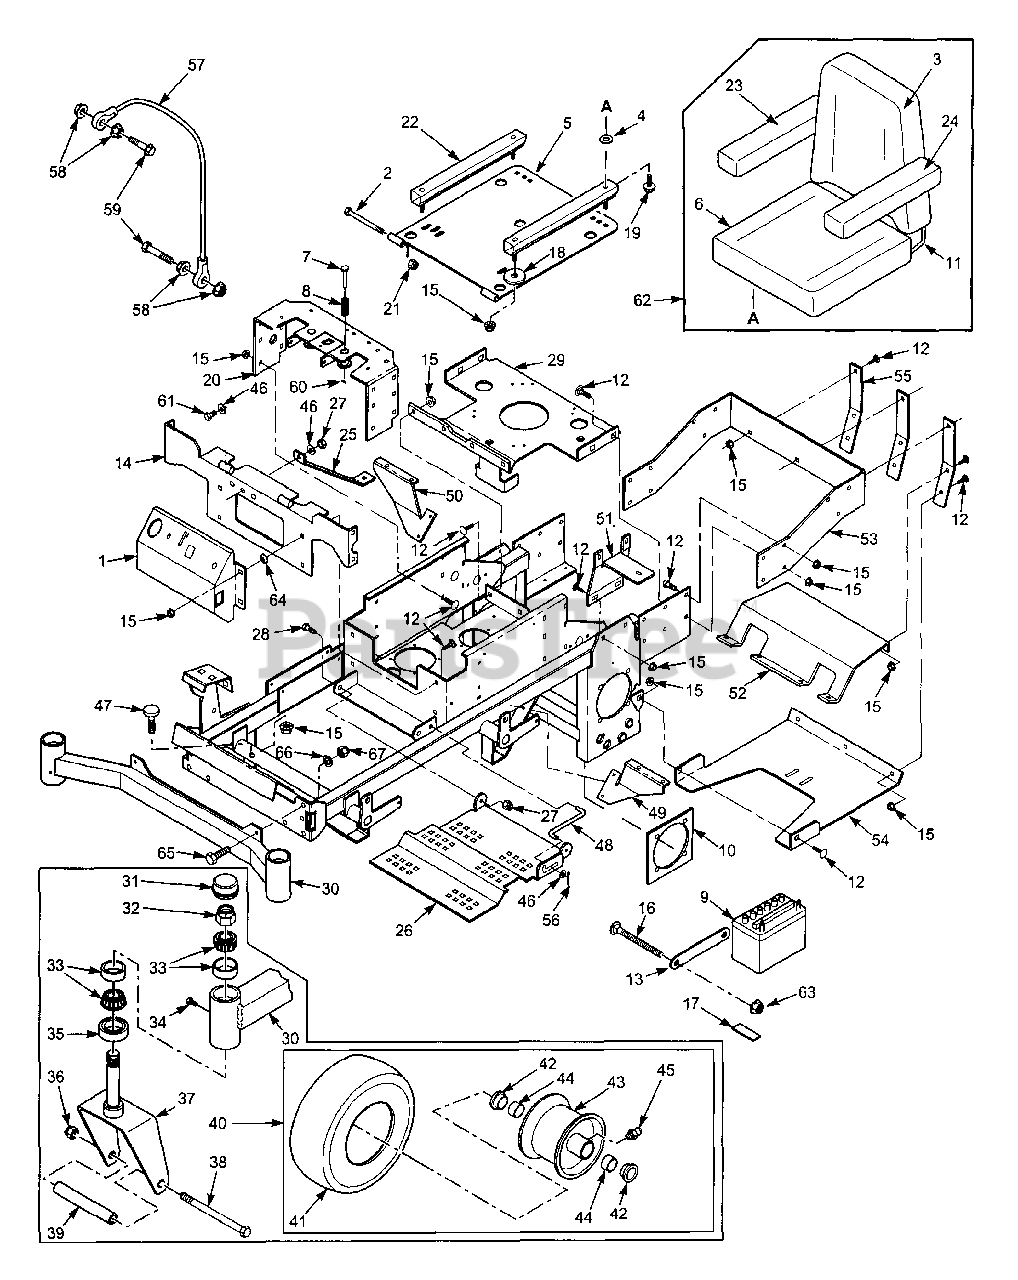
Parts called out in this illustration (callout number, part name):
1	Panel, Instrument
2	Bolt, Hex Head 5/16-18 x 3-1/2"
3	Cushion, Back
4	Flatwasher, 3/8-.406 x 1.5 x .179
5	Plate, Seat Mounting
6	Cushion, Lower Seat
7	Pin Retainer, spring
8	Spring
9	Battery
10	Plate, Wheel Motor Mounting
11	Pan, Seat Mounting
12	Bolt, Carr 5/16-18 x 3/4"
13	Plate, Battery Mounting
14	Weldment, Seat Plate Mounting
15	Nut, Serr. Flange 5/16-18
16	Bolt, Carr. 1/4-20 x 6"
17	Pad, Rubber
18	3/8 Flatwasher, 1-1/2" x 7 ga.
19	Bolt, Carr. 5/16-18 x 1"
20	Weldment, Seat Brace
21	Nut, Elastic Stop 5/16-18
22	Seat Track Assy
23	Arm Pad, RH
24	Arm Pad, LH
25	Brace, Seat Plate
26	Footplate
27	Nut, Elastic Stop 3/8-16
28	Bolt, Hex Head 3/8-16 x 1"
29	Plate, Engine Mounting
30	Weldment, Caster Support
31	Cap, Grease
32	Nut, Elastic Stop 1.0-14
33	Bearing Set
34	Plug, 1/4-28
35	Seal, 2.0" OD x 1.625" ID
36	Nut, Elastic Stop 1/2-13
37	Yoke, Front Caster Wheel
38	Bolt, Hex Head 1/2-13 x 7-1/2"
39	Sleeve
40	Caster Wheel Assembly
41	Tire, 13 x 5.0-6 Smooth
42	Bushing
43	Rim
44	Bearing
45	Fitting, Grease
46	Flatwasher, 3/8-.391 x .938 x.105
47	Stud, Rubber Stop
48	Rod, Footplate Prop
49	Bracket, Lower LH Fuel Tank
50	Bracket, Fuel Tank Front
51	Bracket, Fuel Tank Rear
52	Heatshield
53	Bumper, Rear
54	Plate, Skid
55	Bracket, Support
56	Hair Pin Cotter, .080 x 1.19
57	Cable, Seat Stop
58	Nut, Serr. Flange 1/4-20
59	Bolt, Hex Head 1/4-20 x 1-1/4"
60	Roll Pin, Spring 5/32 x 3/4"
61	Bolt, Hex Head 3/8-16 x 1-1/4"
62	Seat Assembly
63	Nut, Elastic Stop 1/4-20
64	Push Nut, 5/16
65	Bolt, Hex Head 7/16-14 x 1-1/4"
66	Lockwasher, 7/16"
67	Nut, Elastic Stop 7/16-14
